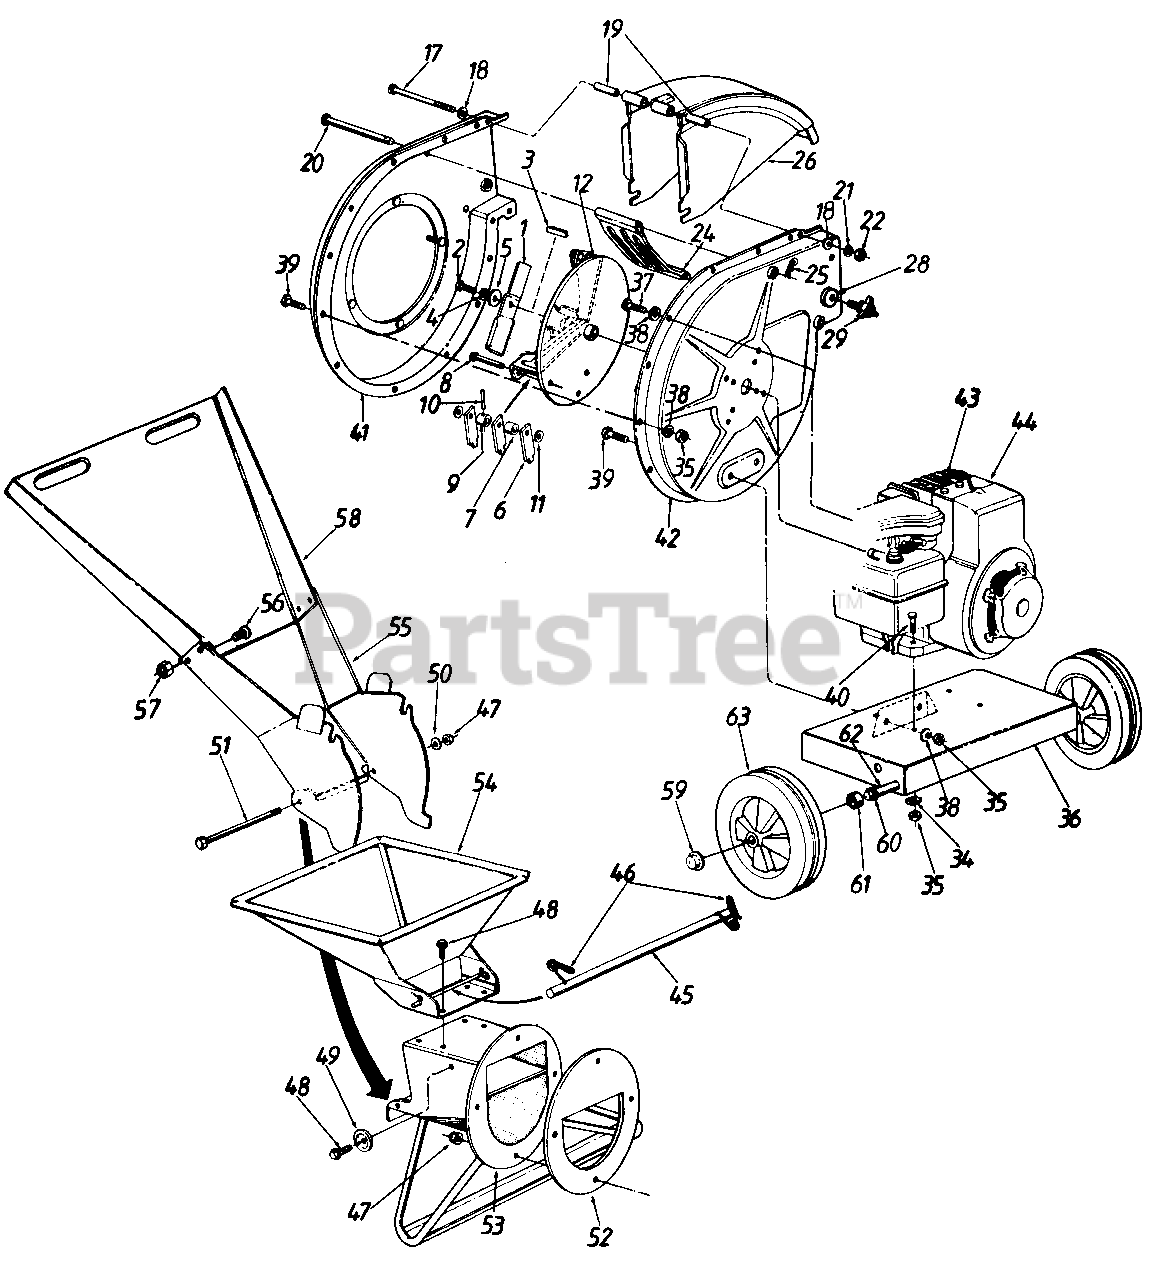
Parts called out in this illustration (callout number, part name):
3	Sq. Key 1/4 x 2.0" Lg.
4	L-Wash. 3/8" I.D. H.D.
5	Fl-Wash. .406" I.D. x 1.25" O.D. Hdn.
6	Flail
7	Flail Spacer
8	Clevis Pin .496" Dia.
9	Flail Spacer w/.160" Dia. Hole
10	Spring Roll Pin 1.12" Lg.
11	Fl-Wash. .531" I.D. x .94" O.D.
12	Impeller Ass'y.
17	Hex Bolt 1/4-20 x 4.0" Lg.
18	Fl-Wash. .344" I.D. x .875" O.D.
19	Chute Hinge Spacer 1.66" Lg.
20	Clevis Pin .5" Dia. x 4.62" Lg.
21	L-Wash. 1/4" I.D.
22	Hex Nut 1/4-20 Thd.
25	Internal Cotter Pin 3/8" Dia.
28	Bell-Wash. .345" I.D. x .88"
29	Hand Knob
34	Spec. L-Wash. 5/16" I.D.
35	Hex Nut 5/16-18 Thd. (Grade 5)
36	N/638 Shredder Frame
37	Hex Bolt 5/16-24 x .75" Lg.
38	L-Wash. 5/16" I.D.
39	Hex Bolt 5/16-18 x .75" Lg. (Grade 5)
40	Hex Bolt 5/16-18 x 1.75" Lg.*
43	Spark Plug Boot
44	Engine
45	Release Bar
46	Torsion Spring 1.06" Lg.
47	Elastic Lock Nut 5/16-18 Thd.
48	Hex Wash. Hd. Self-Tap Scr. 5/16-18 x .75" Lg.
49	Stop Washer
50	Fl-Wash. 5/16" 1 .D.
51	Hex Bolt 5/16-18 x 8.38" Lg.
52	Back-Up Plate
53	Inlet Guide Ass'y.
57	Hex L-Nut 1/4-20 Thd.
60	Fl-Wash. .64" I.D. x 1.24"
61	Spacer .64" I.D. x .38" Lg.
62	Shredder Axle
63	Wheel Ass'y. Comp.
